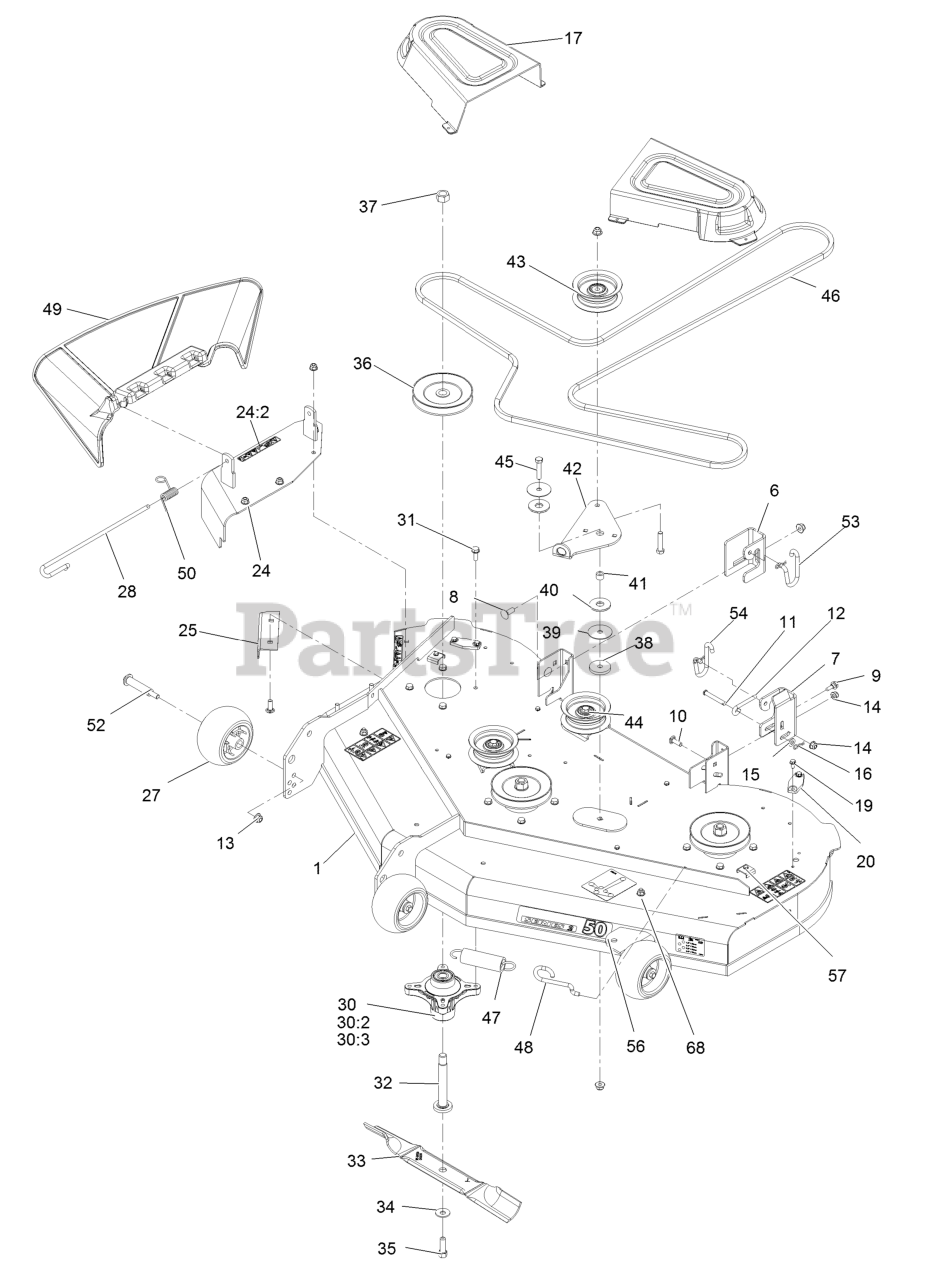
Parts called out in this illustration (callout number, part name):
1	DECK AND DECAL ASM
6	BRACKET-HANGER, RH
7	BRACKET-HANGER, LH
8	BOLT-CARR
9	SCREW-SHOULDER,HWH
10	SCREW-CARR
11	PIN-CLEVIS
12	ROD-LEVEL, DECK
13	NUT-HF, NI
14	NUT-HF, NI
15	WASHER-PLAIN
16	PIN-COTTER
17	COVER-BELT
19	SCREW-HWH
20	COVER-WASHOUT PORT
24	COVER ASM W/DECAL
24:2	DECAL-DANGER
25	BAFFLE-CUTOFF
27	ROLLER-SCALP, ANTI
28	PIN-CHUTE
30	SPINDLE ASM
30:3	BEARING-BALL
31	SCREW-TAPTITE
32	SHAFT-SPINDLE
33	BLADE-HI LIFT
34	WASHER-BELLEVILLE
35	SCREW-HH
37	NUT-HEX
38	WASHER-PLAIN
40	WASHER-FRICTION, COMPOSIT
42	ARM-IDLER
44	WASHER-FLAT
45	SCREW-HH
46	V-BELT
47	SPRING-EXTENSION
48	HOOK-RETURN, SPRING
49	DEFLECTOR-DISCHARGE
50	SPRING-TORSION
52	BOLT-SHOULDER
53	LINK-RETENTION, DECK (RH)
54	LINK-RETENTION, DECK (LH)
56	DECAL-SERIES 2 - 50
57	SCREW-TAPTITE
68	SCREW-HH
